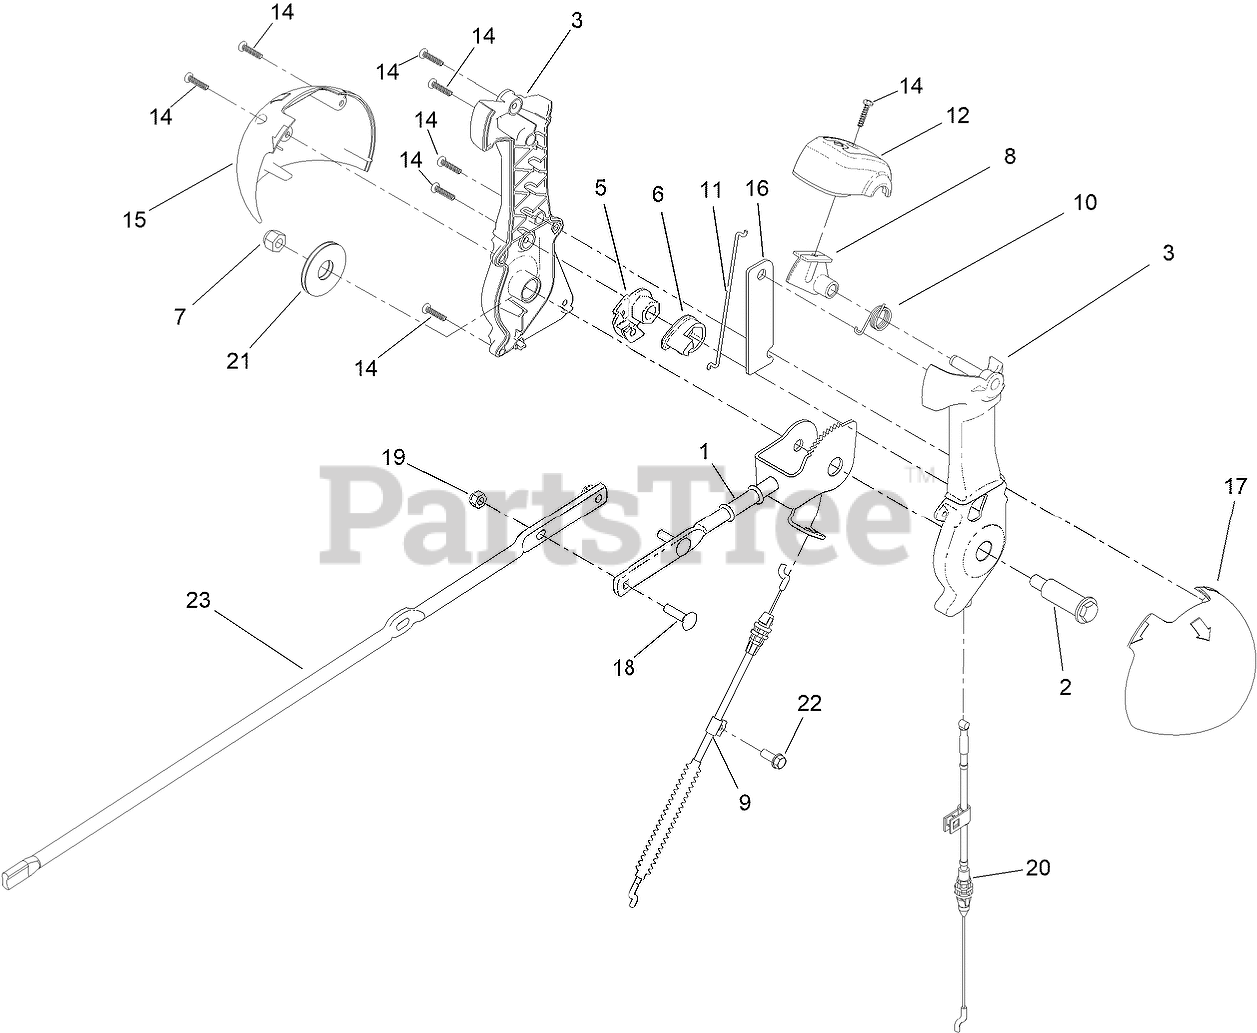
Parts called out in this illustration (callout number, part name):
1	ROD-CONTROL, CHUTE
2	SCREW-SHOULDER, HWH
3	CHUTE CONTROL LEVER ASM
5	LEVER-CABLE, DEFLECTOR
6	PAWL-LATCH
7	NUT-HEX
8	TRIGGER-LATCH
9	CABLE-CONTROL, DEFLECTOR
10	SPRING-TORSION
11	LINK-LATCH
12	CAP-LEVER
14	SCREW-PPH
15	GLOBE-QUICKSTICK, RH
16	PLATE-STIFFNER
17	GLOBE-QUICKSTICK, LH
18	BOLT-CARR
19	NUT-HEX
20	CABLE-RELEASE, CHUTE
21	WASHER-FRICTION, COMPOSITE
22	SCREW-HWH
23	ROD-CHUTE
